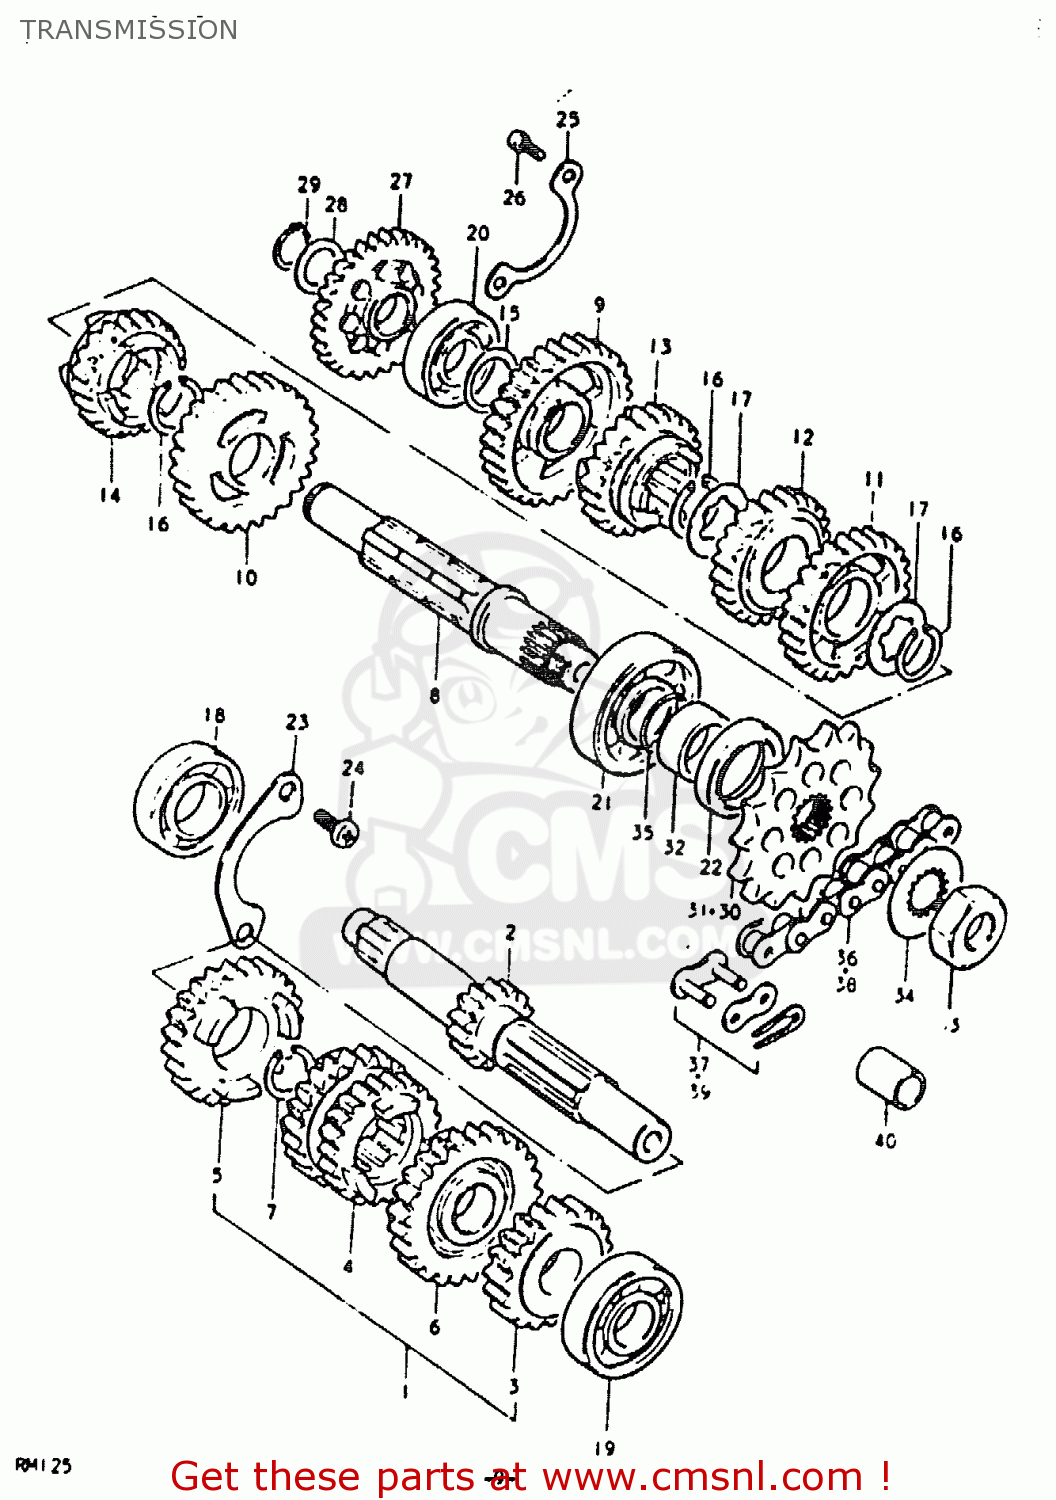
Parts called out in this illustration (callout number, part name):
1	SHAFT,COUNTER
2	SHAFT,COUNTER
3	GEAR,SECOND DRIVE
4	GEAR,THIRD DRIVE
5	GEAR,FIFTH DRIVE
6	GEAR,SIXTH DRIVE
7	CIRCLIP
8	SHAFT,DRIVE
9	GEAR,FIRST DRIVEN
10	GEAR,SECOND DRIVEN
11	GEAR,THIRD DRIVEN
12	GEAR,FOURTH DRIVEN
13	GEAR,FIFTH DRIVEN
14	GEAR,SIXTH DRIVEN
15	WASHER,THRUST
16	CIRCLIP
17	WASHER,LOCK
18	Bearing
19	BEARING
20	BEARING, RH
21	BEARING(20X47X14)
22	SEAL,OIL(25X40X7)
23	RETAINER,CNTR SHAFT BEARING
24	SCREW 6X12
25	PLATE,DRIVESHAFT BEARING
26	SCREW
27	GEAR,KICK STARTER IDLE
28	WASHER,THRUST
29	CIRCLIP,15MM
31	SPROCKET,ENGINE
32	SPACER(20X25X12.5)
33	NUT
34	WASHER,LOCK
35	O RING(D:1,ID:19.5)
38	CHAIN ASSEMBLY,DRIVE
39	JOINT ASSEMBLY,CHAIN
40	CUSHION
